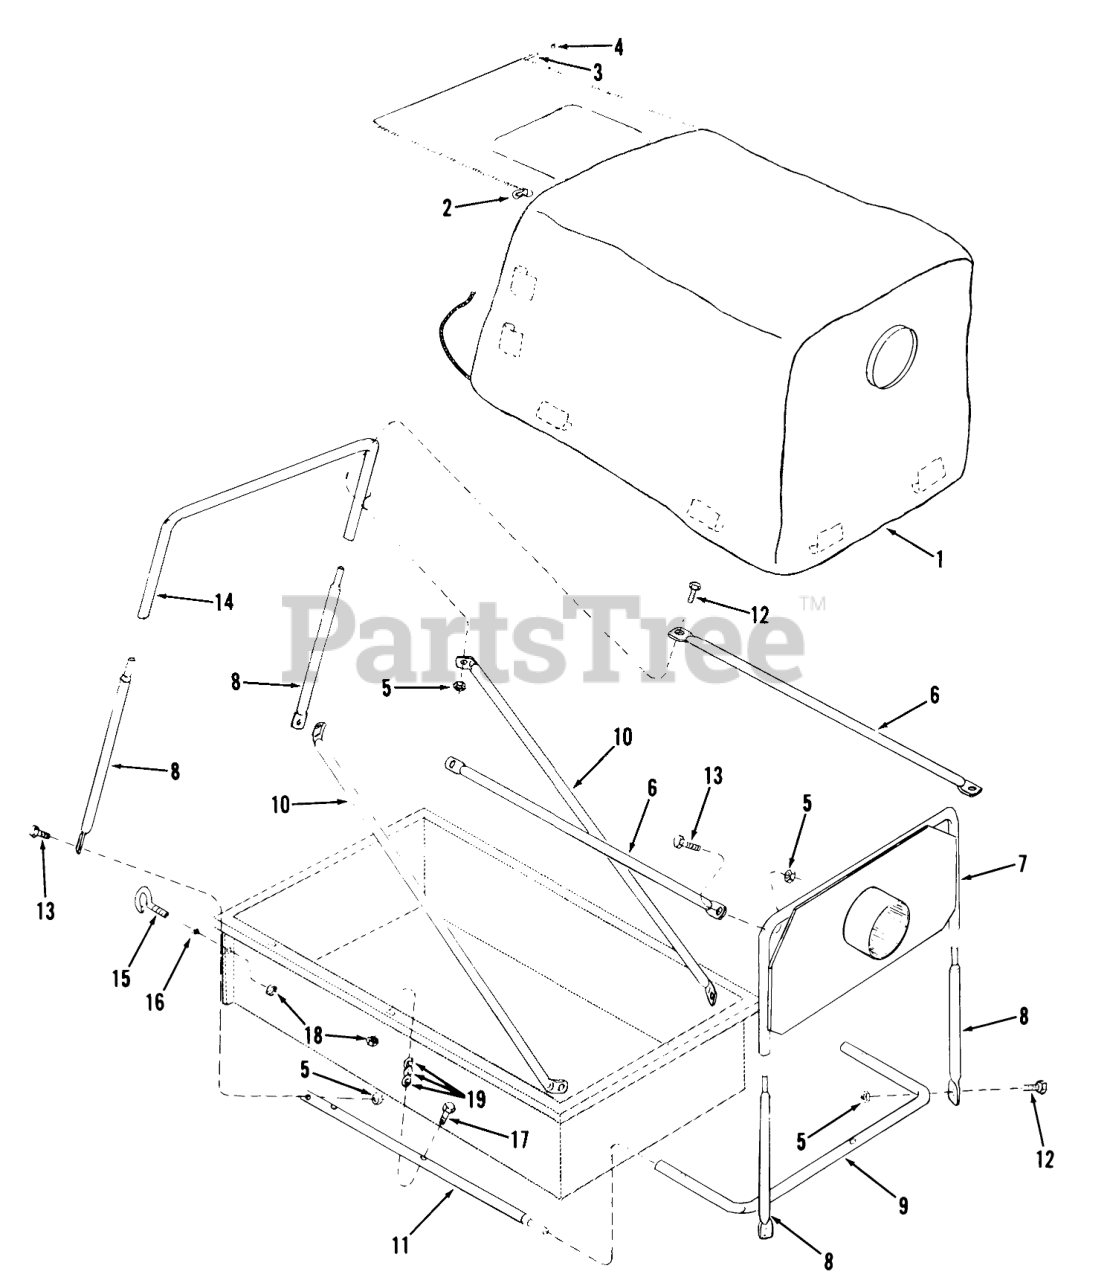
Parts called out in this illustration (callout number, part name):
1	Cart Cover
2	5/16 DIA HOOK
3	CANOPY ROD
4	RUBBER CAP
5	Nut
6	Top Tube
7	Front Hose Adapter
8	Upright Brace
9	U-Tube
10	Cross Tube
11	Side Tube
12	Bolt
13	Bolt
14	U-Tube
15	EYE BOLT
16	Nut
17	Bolt 1/4-20 X 1 1/2
18	Nut
